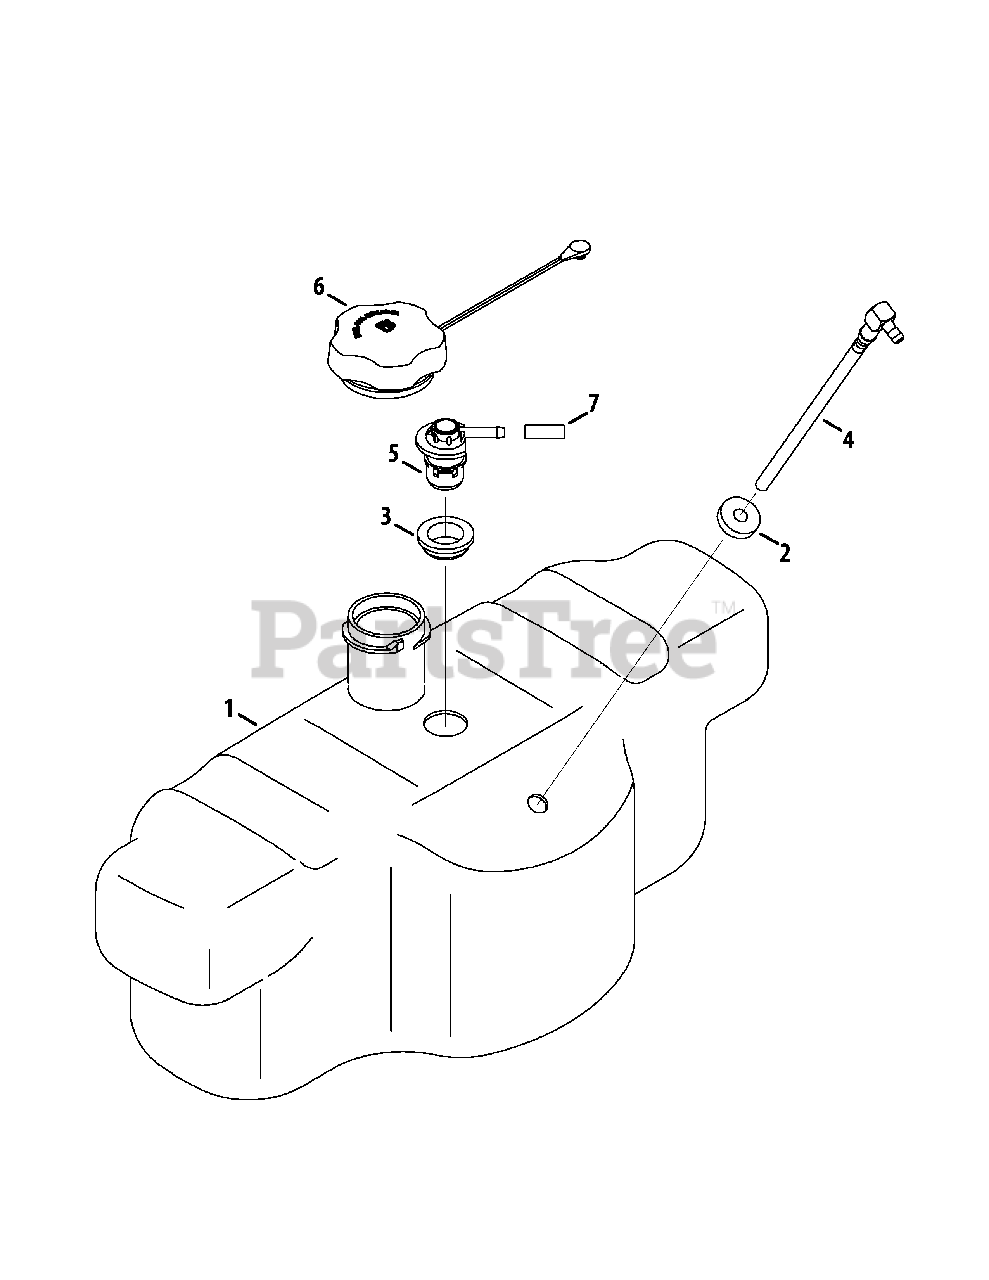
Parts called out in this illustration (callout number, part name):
1	Fuel Tank
2	Fuel Tank Bushing
3	Rubber Grommet
4	Fuel Pickup Fitting
5	Rollover Valve
6	Fuel Cap
7	Vent Hose
